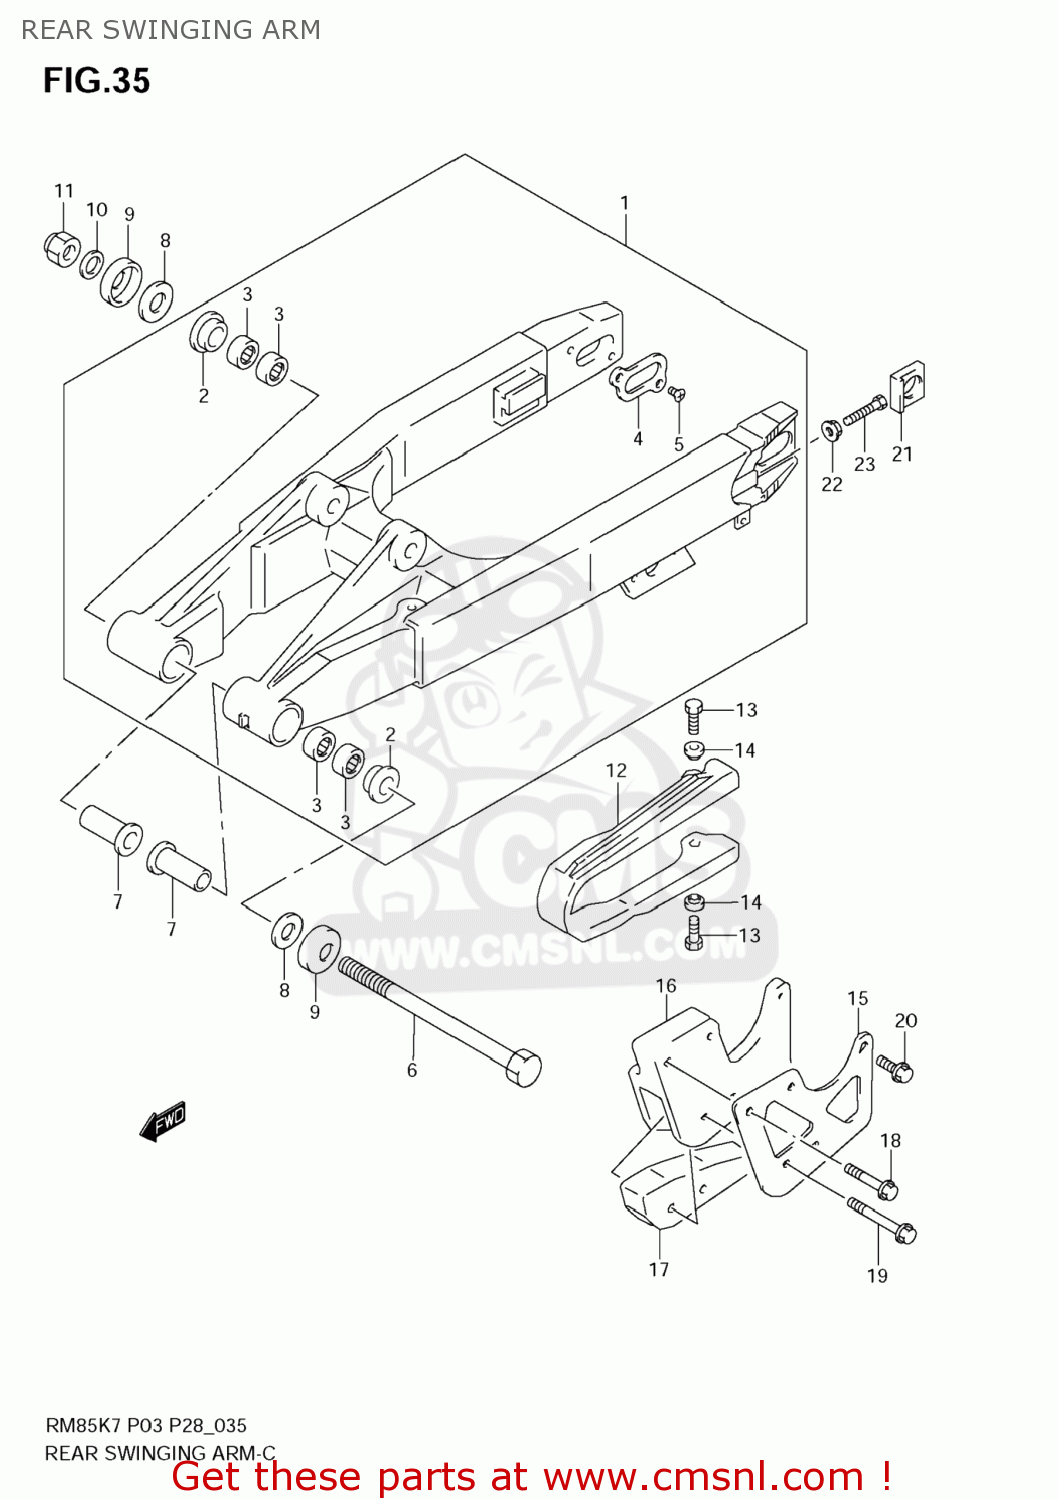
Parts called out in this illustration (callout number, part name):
1	SWINGINGARM ASSY,RR
2	BUSHING,SWGARM PIVOT
3	BEARING(17X24X20)
4	PLATE,SWGARM RR
5	SCREW
6	SHAFT,RR SWINGINGARM PIVOT
7	SPACER,RR SWGARM PIVOT
8	WASHER
9	COVER,SWGARM PIVOT
10	WASHER
11	NUT
12	BUFFER,CHAIN TOUCH DEFENSE
13	BOLT(6X16)
14	WASHER
15	PLATE,GUIDE CHAIN OUTER
16	GUIDE,CHAIN
17	DEFENSE,CHAIN GUIDE
18	BOLT(6X30)
19	BOLT(6X40)
20	BOLT(6X16)
21	WASHER,CHAIN ADJUSTER
22	NUT
23	BOLT(8X43)
